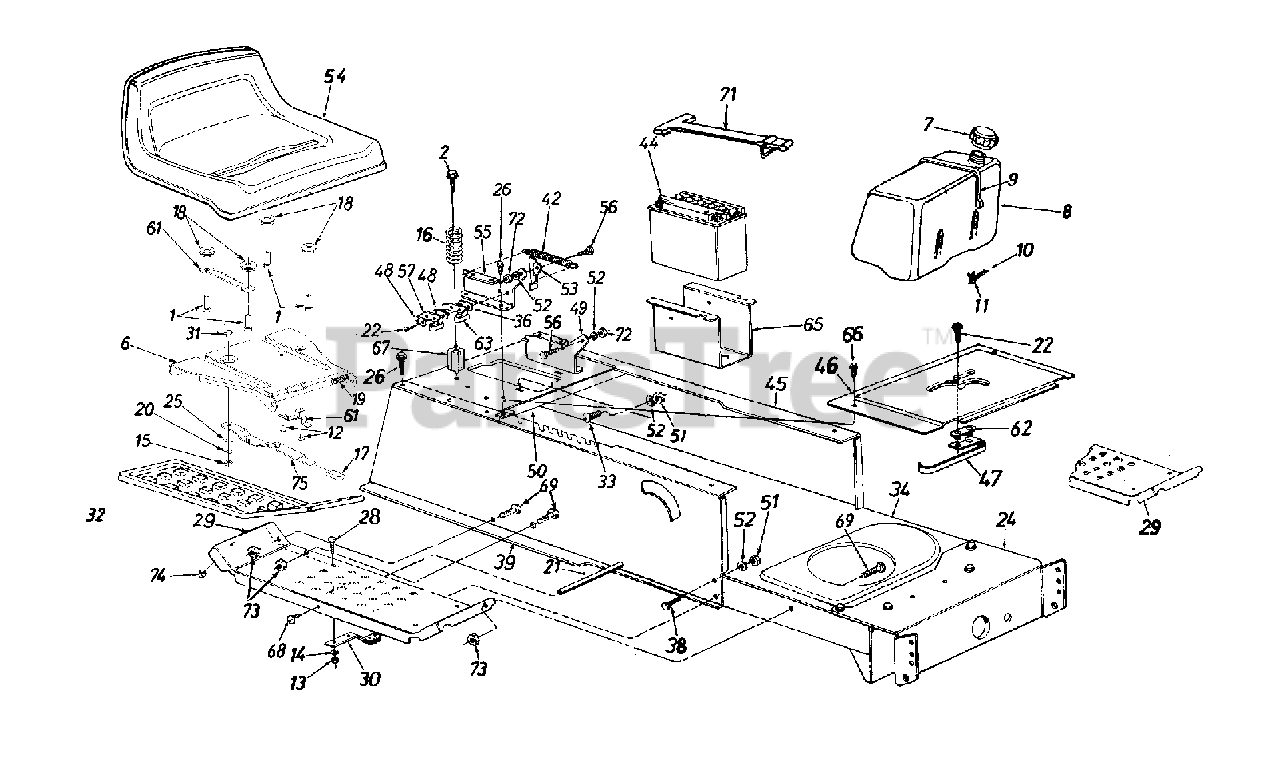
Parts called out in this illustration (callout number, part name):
1	Shoulder Screw 3/8-16 x .5
2	Hex Wash. Hd. Tap Scr. 5/16-18 x 3.25" Lg.
9	Tie Strap
10	Fuel Line
12	Hex B-Tapp Scr. #10-16 x .38
13	Hex Nut 1/4-20 Thd.
14	L-Wash. 1/4" I.D.
15	Lock Nut 1/4-20
16	Compression Spring
19	Compression Spring
20	Spr. Wash. .265 x .562 x .025
21	Running Board Rod
22	Hex Wash. Hd. AB-Tap Scr. #8 x .50" Lg.
25	Fl. Wash. .344 x .62 x .03
26	Hex Wash. Hd. AB-Tap Scr. 5/16 x .75" Lg.
28	Carriage Bolt 1/4-20 x .75"
31	Shld. Bolt 1/4-20 Thd.
32	Rubber Foot Pad-L.H
36	Insulator Boss Plate
38	Hex Bolt 5/16-18 x .75" Lg.
44	12-V Battery
47	Safety Switch (Reverse)
48	Insulator Plate
52	L-Wash. 5/16" I.D.
53	Seat Lift Brkt.
54	Seat - Grey
56	Shld. Bolt .437" Dia. x .268"
57	Spring Switch (Seat-Outer)
61	Seat Selector
62	Insulator Nut Plate
63	Safety Switch (Seat-Inner)
66	Tr. Mach. B-Tap Scr. #10 x .5" Lg.
67	Spring Spacer
68	Truss Mach. Scr. 5/16-18 x .75"
69	Hex Bolt 5/16-18 x .75" Lg.
71	Battery Retainer Strap
72	Hex Nut 5/16-18 Thd.
73	Hex Sems Nut 5/16-18 Thd.
74	Hex Sems Nut 1/4-20 Thd.
